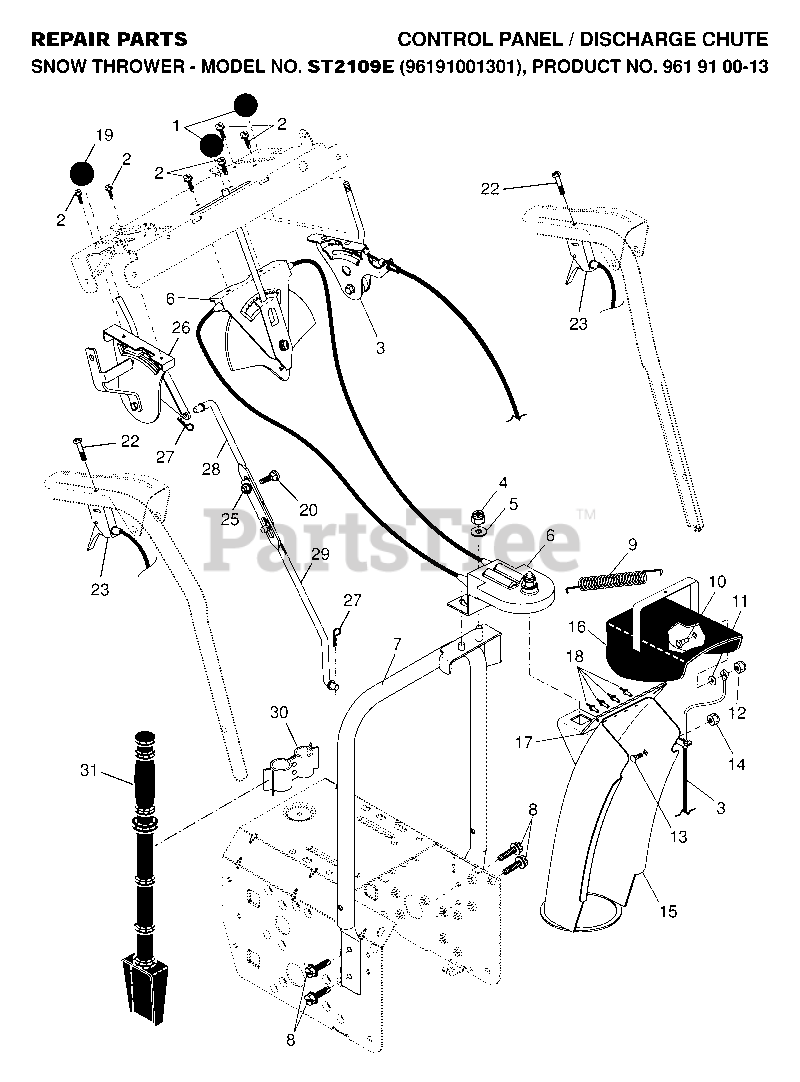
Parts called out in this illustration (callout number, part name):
1	KNOB, LEVER
2	SCREW #10-24 X 5/8
3	CONTROL.CABLE.DEFLECTOR
4	NUT
6	CONTROL.CABLE.CHUTE.RO
7	SUPPORT, PIVOT
8	SELF-TAPPING SCREW 5/16-18X3/4
10	BOLT, SHOULDER
11	WASHER, NYLON FRICTION
12	LOCKNUT
13	BOLT
14	NUT, LOCK 5/16-18
17	SEAL, DEFLECTOR
18	RIVET BLIND
19	RP KNOB, SPEED CONTROL LEVER
23	STEERING.CONTROL.SNOW THROWER
25	NUT, HEX FLANGE 5/16-18
26	HEAD ASSY SPEED
27	SPRING RETAINER
28	ROD, UPPER SPEED CONTROL
29	ROD, LOWER SPEED CONTROL
30	CLAMP.ASM.CLEANOUT.TOOL.SNOW
31	CLEAN OUT TOOL
